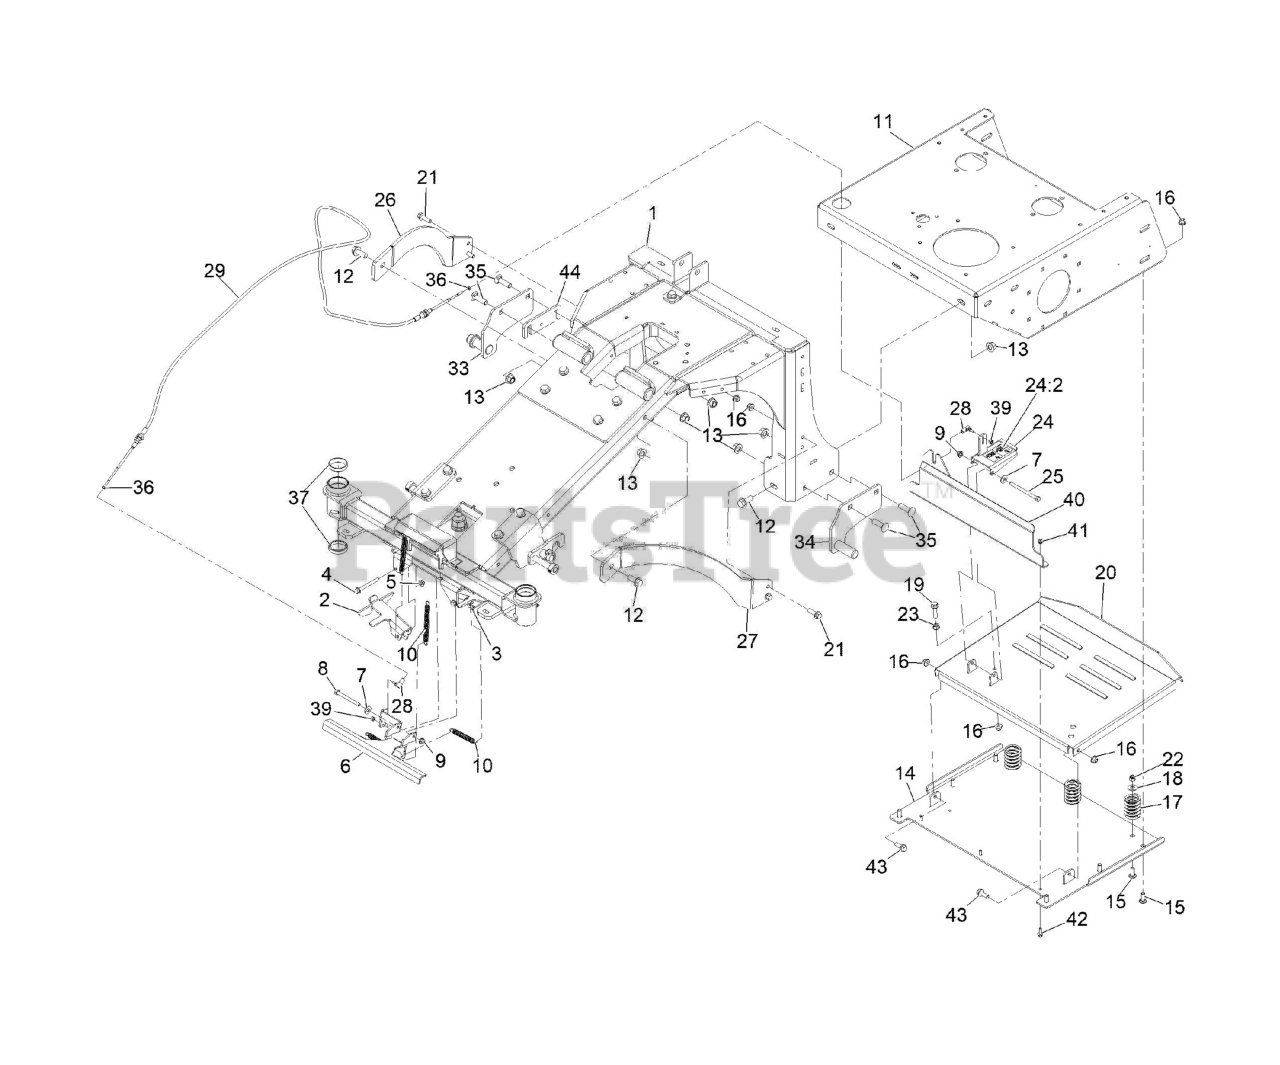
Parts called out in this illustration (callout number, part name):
1	Front Frame ASM
2	WING-CASTER RH
3	WING-CASTER LH
4	SCREW-HHF
5	Nut-Hex Flange
6	ARM-BODY, LCS
7	Washer-Flat
8	SCREW-HH
9	NUT-HF, NI
10	SPRING-EXTENSION
11	REAR FRAME ASM
12	SCREW-HHF
13	Nut-Lock 1/2-13
14	FRAME BASE
15	SCREW-CARR
16	NUT-HF, NI
17	SPRING-COMPRESSION
18	Washer-Flat
19	SCREW-HHF
20	WLD, FOOTPLATE, AE
21	SCREW-HHF
22	NUT-LOCK, NI
23	NUT-HEX FLANGE
24	PEDAL-FOOT
24:2	Decal-Lock, Caster
25	SCREW-HH
26	BRACE-FRAME, RH
27	BRACE-FRAME, LH
28	BALL JOINT-SS
29	ZPLUG LOCKING CASTER CABL
33	PIVOT-BRAKE, RH
34	PIVOT-BRAKE, LH
35	SCREW-CARR
36	Nut,Hex Jam Mch Scr,10-32,Sst
37	BEARING-CUP, TAPERED
39	Nut,NYL Lock,#10-32,ST/ST 18-8
40	SHIELD-HEAT, MUFFLER
42	SCREW-HHF
43	SCREW-HHF 3/8-16 X 1
44	Plate-Spacer-Zplug
